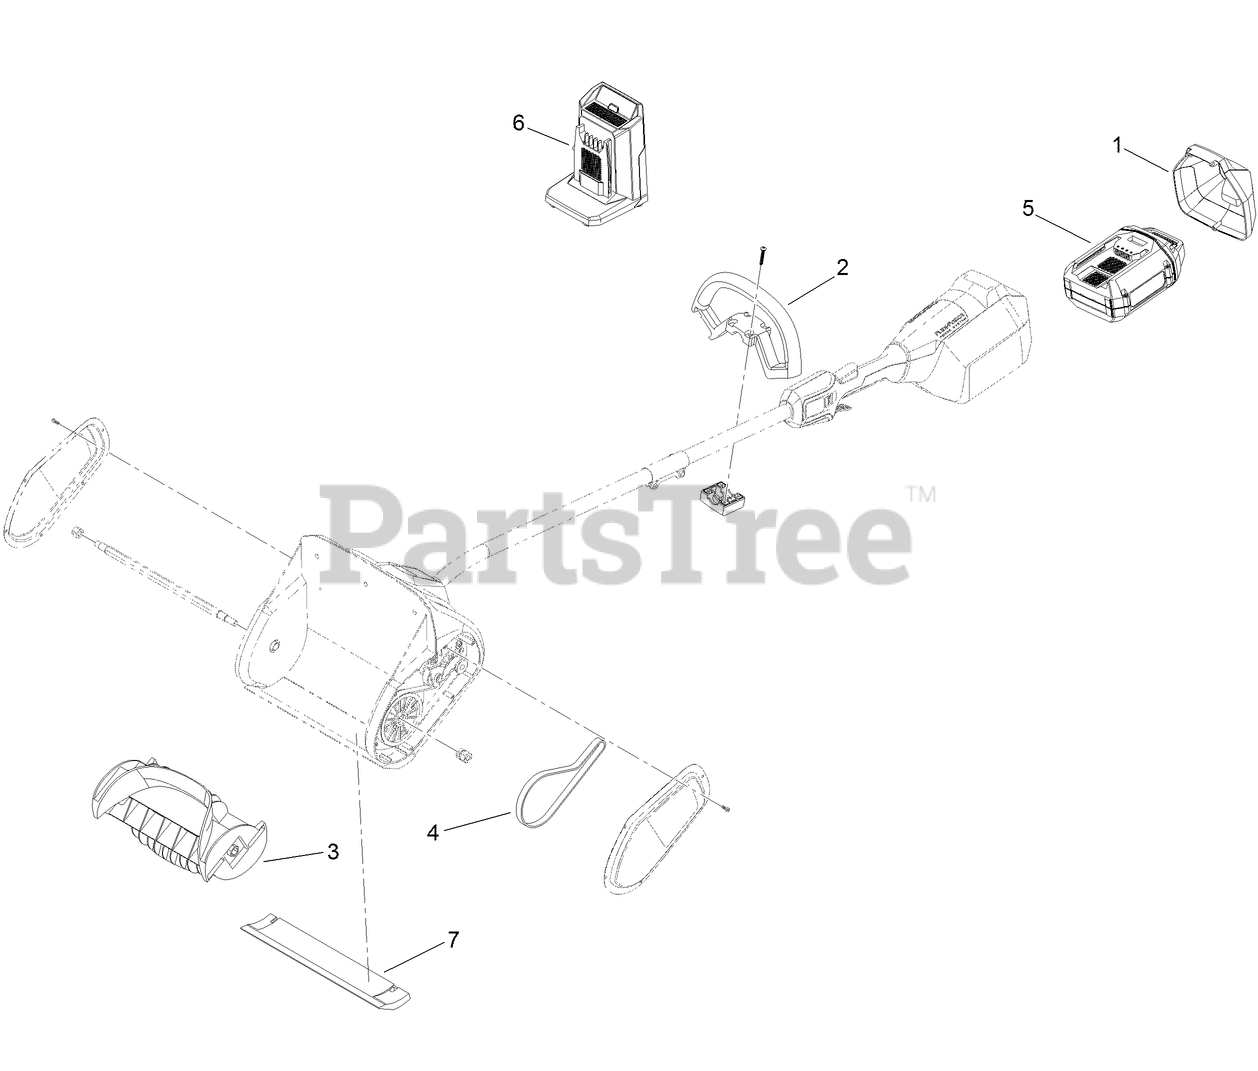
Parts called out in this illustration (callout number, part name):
1	COVER-BATTERY
2	HANDLE-TRIMMER
4	BELT-DRIVE
5	BATTERY-LI ION, 60V 2.5 AH
6	CHARGER-BATTERY, 60V 2 AMP
7	SCRAPER
